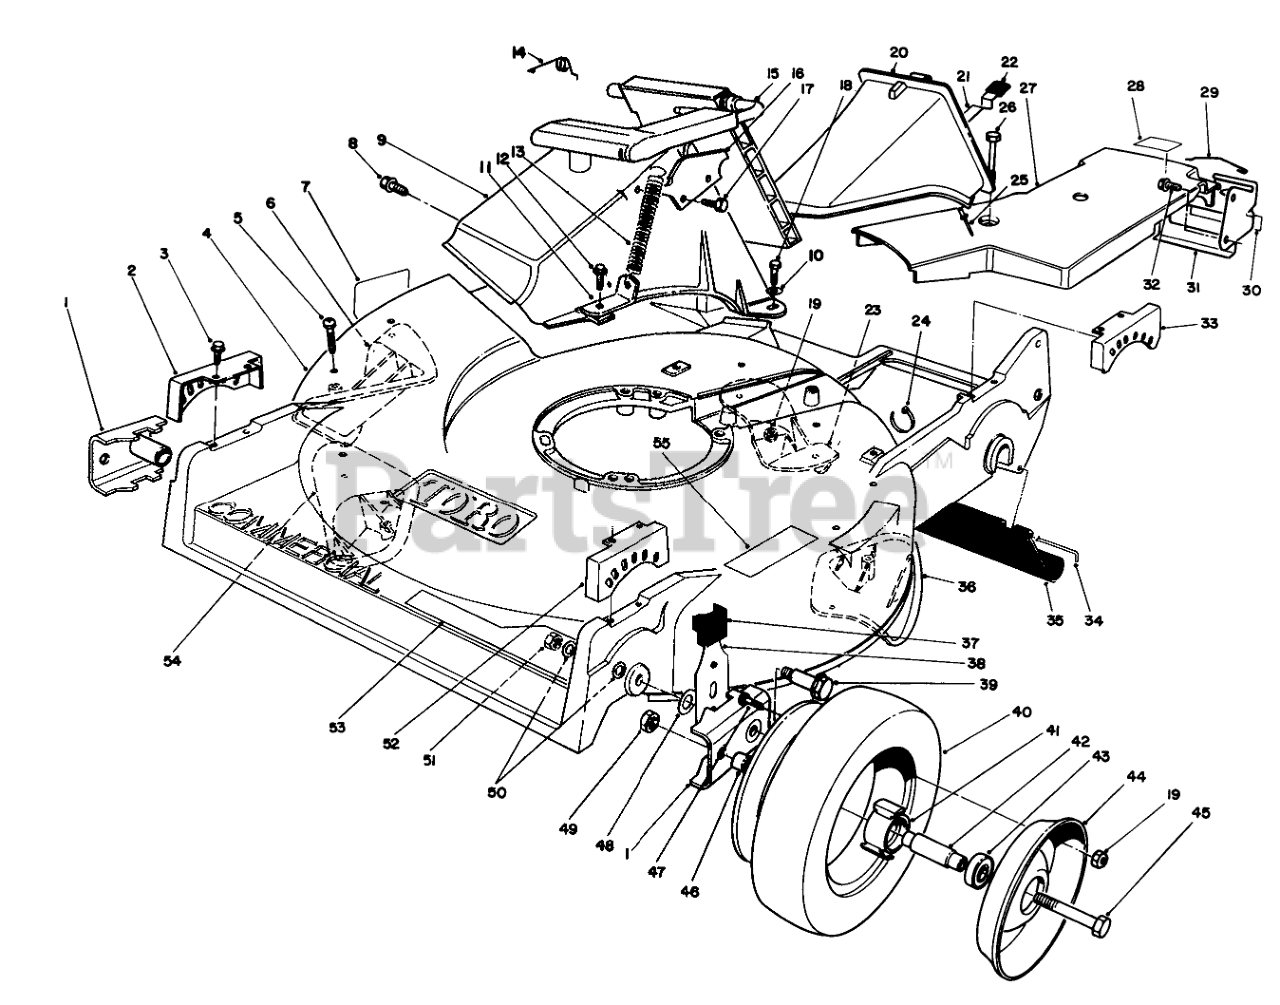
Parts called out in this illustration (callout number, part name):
1	ARM-PIVOT, FRONT
2	QUADRANT-FRONT, RH
3	SCREW-HWHTF
4	Housing-Commercial (Incl. Ref. #7, 53, & 55)
5	SCREW-PPH
6	KICKER
7	DECAL-DANGER
8	SCREW AND WASHER ASM
9	DISCHARGE TUNNEL
10	WASHER-FLAT
11	Bracket-Spring
12	SCREW-HWH
13	SPRING-DOOR
14	RETAINER-DOOR
15	DOOR ASSEMBLY
16	DOOR LATCH PLATE
17	SCREW-PLASTITE
18	SCREW-HH
19	NUT-LOCK, NI
20	Plug-Discharge (Incl. Ref. #21, 22, & 25)
21	LATCH-PLUG, DISCHARGE
22	GRIP-LATCH
23	KICKER
24	TIE-CABLE
25	RIVET-HEAD, FLAT
26	SCREW-HHFTF
27	COVER-BELT
28	LABEL-GREASE
29	RETAINER-CABLE
30	DECAL-POSITION, GEAR
31	BRKT-TRACTION ADJ.
32	SCREW-HWHTF
33	QUADRANT-REAR, LH
34	ROD-SHIELD
35	SHIELD-TRAILING
36	KICKER
37	KNOB-ARM
38	FRONT SPRING ARM ASM
39	WHEEL BOLT
41	HUB-BEARING
42	SPACER-BEARING
43	BEARING-WHEEL
44	Wheel-Half
45	SCREW-HH
46	SPACER-WHEEL
47	SCREW-HH
48	WASHER-THRUST
49	NUT-LOCK, CONE
50	WASHER
51	Nut
52	QUADRANT-FRONT, LH
53	DECAL - RECYCLER
54	KICKER
55	DECAL-INSTRUCTION, SAFETY
